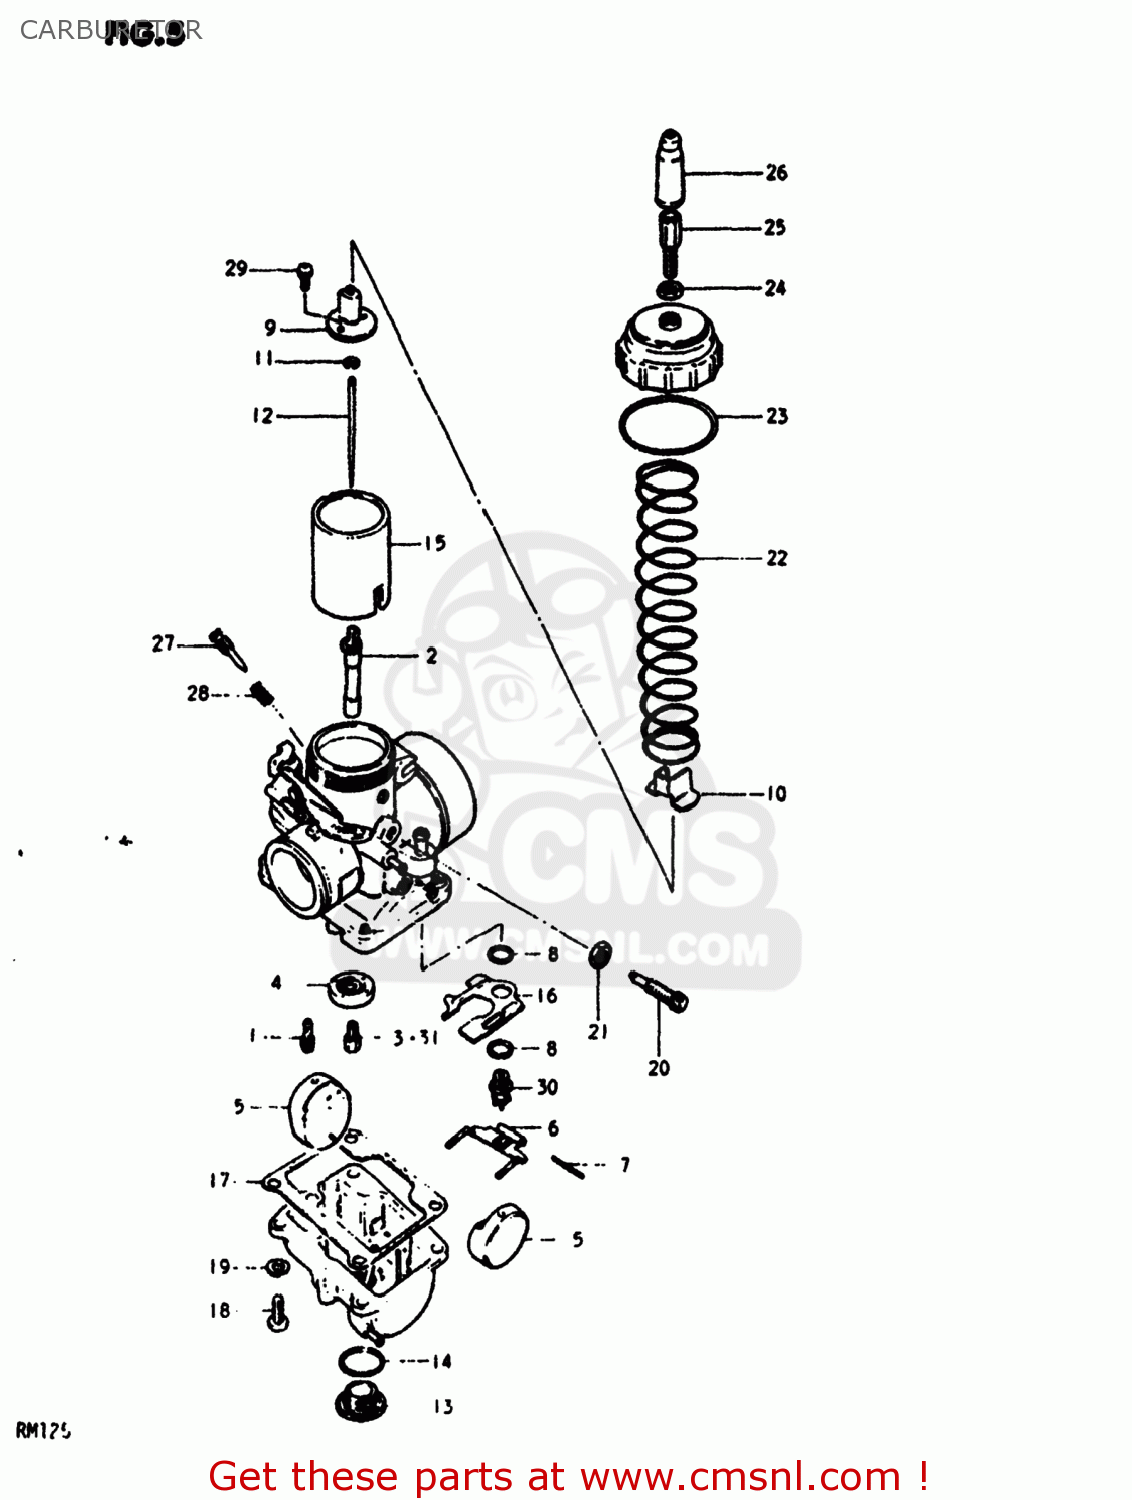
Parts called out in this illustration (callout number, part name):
0	CARBURETOR ASSEMBLY
1	JET
2	JET,NEEDLE
3	JET
4	RING,MAIN JET FIXING
5	FLOAT
6	ARM,FLOAT
7	PIN,FLOAT
8	GASKET,MAIN JET HOLDER (NAS)
9	CONNECTOR
10	COVER,HOLDER
11	CLIP
12	NEEDLE JET
13	PLUG
14	GASKET,DRAIN PLUG
15	VALVE,THROTTLE
16	PLATE
17	GASKET,FLOAT CAHMBER (NAS)
18	SCREW
19	LOCK WASHER
20	ADJUSTER
21	NUT
22	SPRING,THROTTLE VALVE RETURN
23	O-RING,MIXING CHAMBER
24	NUT
25	ADJUSTER,CABLE
26	CAP
27	SCREW,PILOT AIR
28	SPRING
29	SCREW
30	VALVE ASSY,NEEDLE
31	JET
